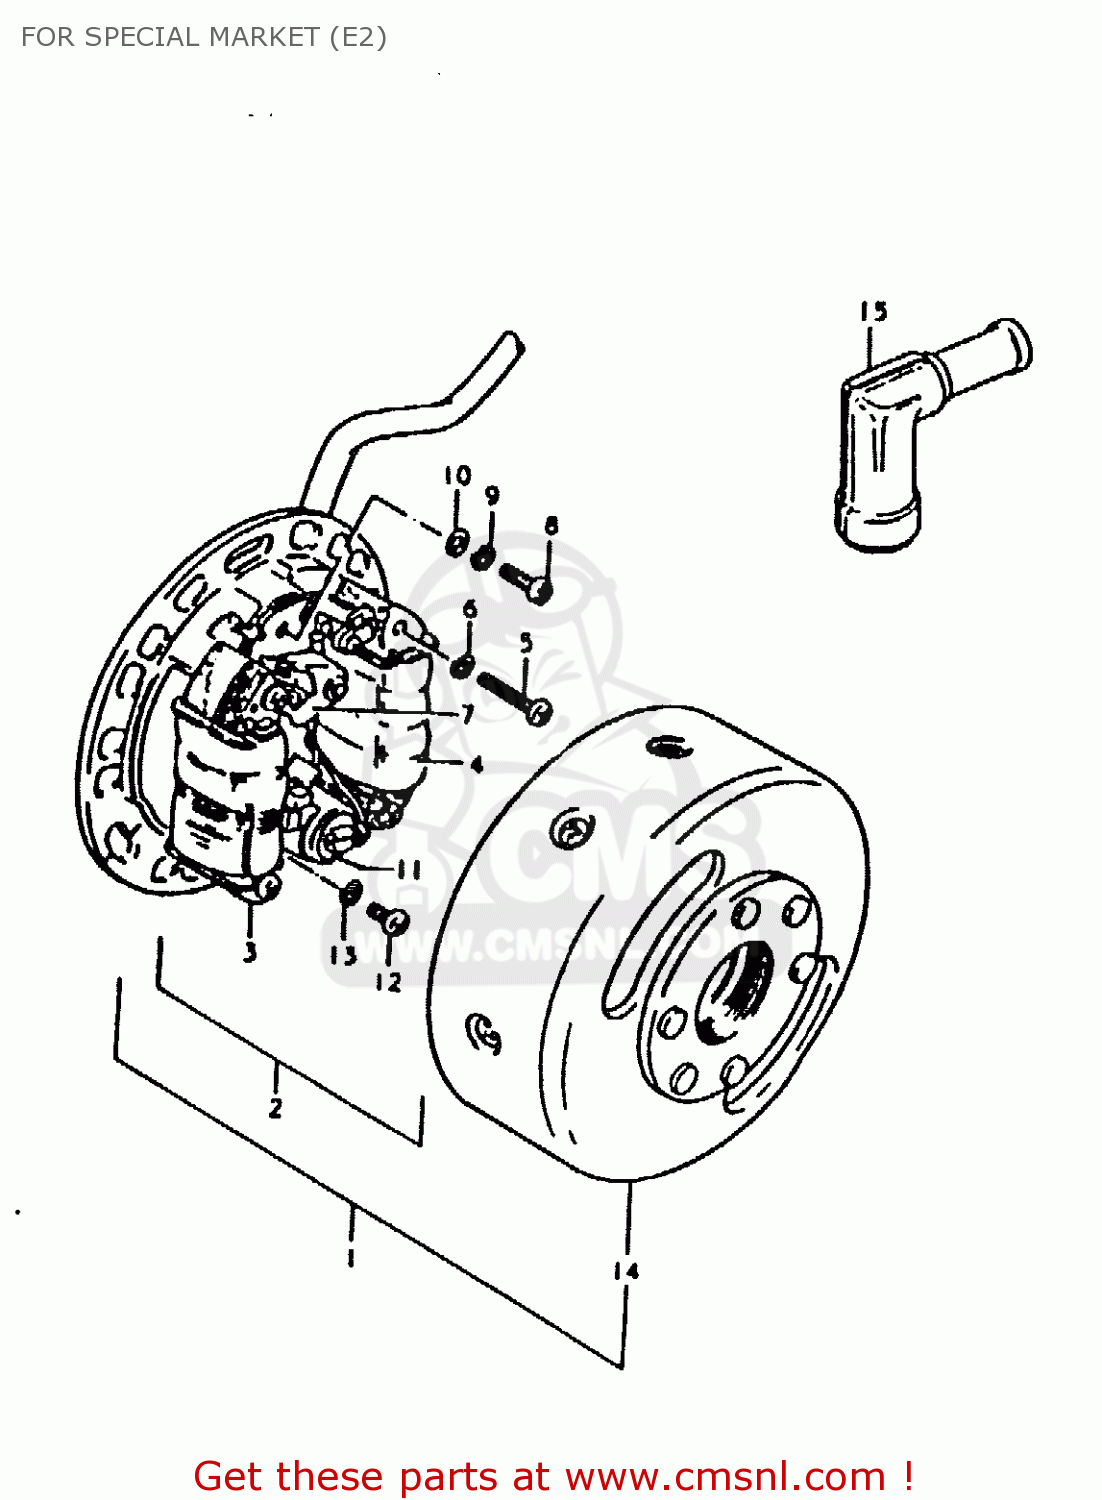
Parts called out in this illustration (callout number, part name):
1	MAGNETO ASSY
2	STATOR ASSY
3	COIL, LIGHTING
4	COIL,PRIMARY
5	SCREW
6	LOCK WASHER
7	POINT ASSY,CONTACT
8	SCREW(4X10)
9	LOCK WASHER
10	WASHER
11	CONDENSER
12	SCREW
13	LOCK WASHER
14	ROTOR, FLYWHEEL
15	CAP,SPARK PLUG
